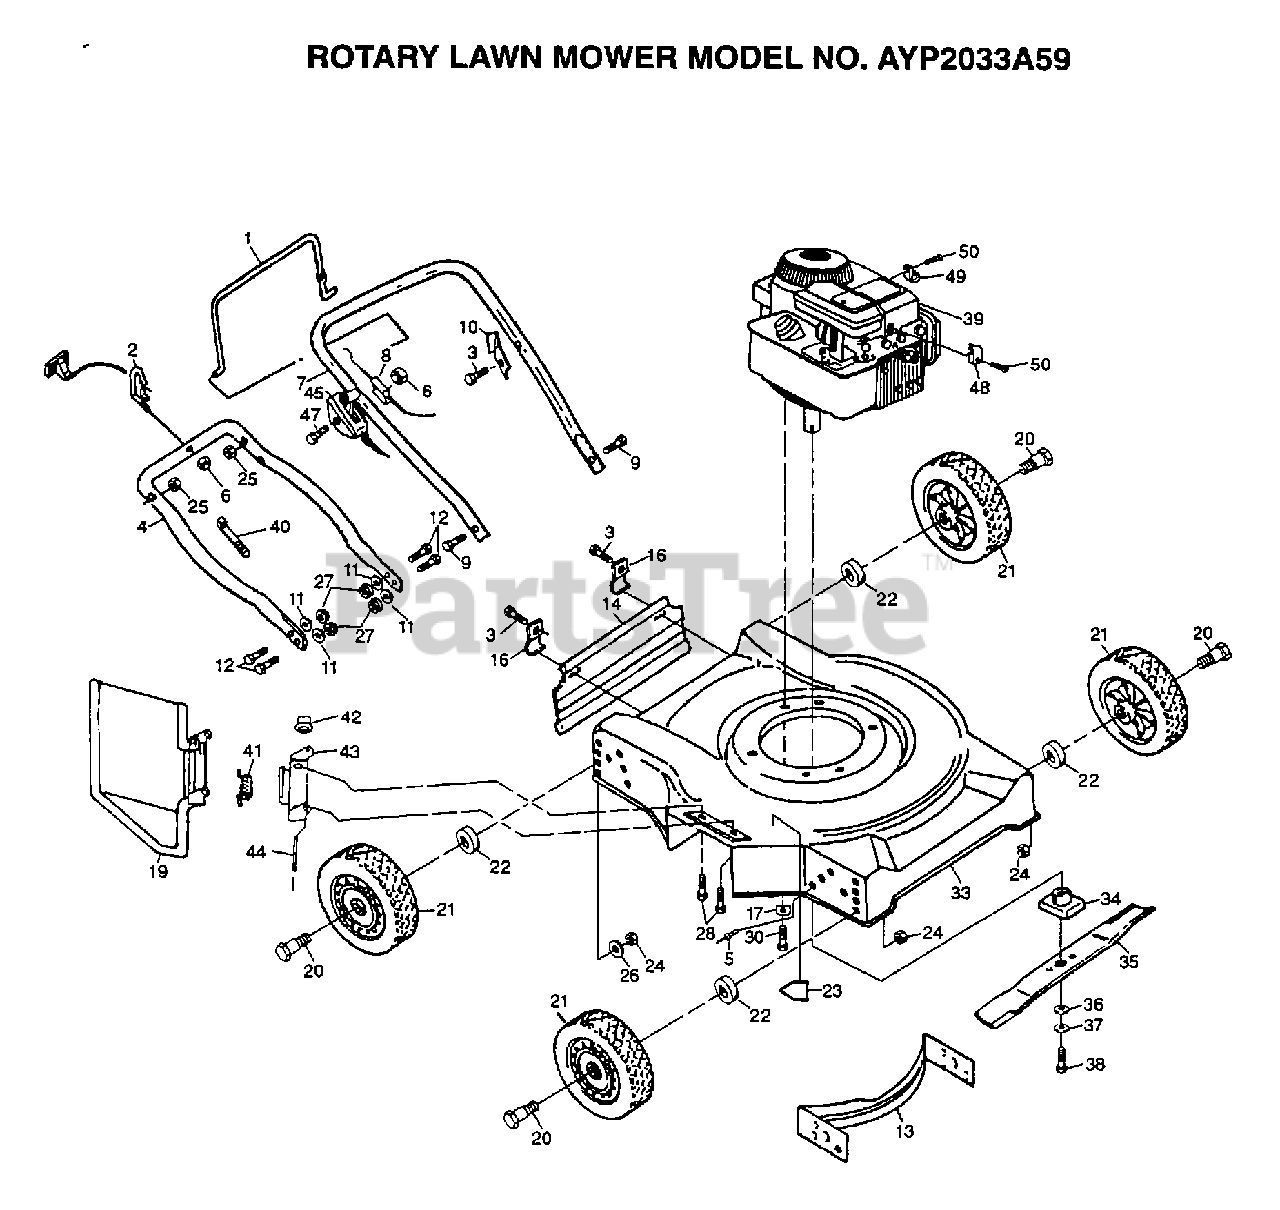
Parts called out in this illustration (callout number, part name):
1	CONTROL BAR PM
2	ROPER GUIDE PM
3	TAPPING SCREW
4	HANDLE LWR PM
5	BLIND RIVET
7	UPPER HANDLE
8	CABLE.CONT.ENG
9	BOLT 1/4-20-1 1/2
10	"BRKT,UPSTOP"
11	STEEL WASHER
14	SKIRT.REAR.20RD.
16	"BRKT,DEFL PM"
19	"GRD,DISCHARGE"
20	AXLE BOLT
21	WHEEL&TIRE
23	DECAL-DANGER PM
24	LOCKNUT PM
27	LOCKNUT
30	SCREW
33	KIT.HSG.20SD.PUSH
34	BLADE ADAPTOR
35	BLADE.STAND.20INC
36	"WASHER,HARDEN"
37	LOCKWASHER
38	SCREW
41	"SPRING,TORSION"
42	PUSH ON SPEED NUT
43	"BRKT,HSG "
48	CABLE CLAMP
49	GUIDE CLIP PM
50	SCREW PM
